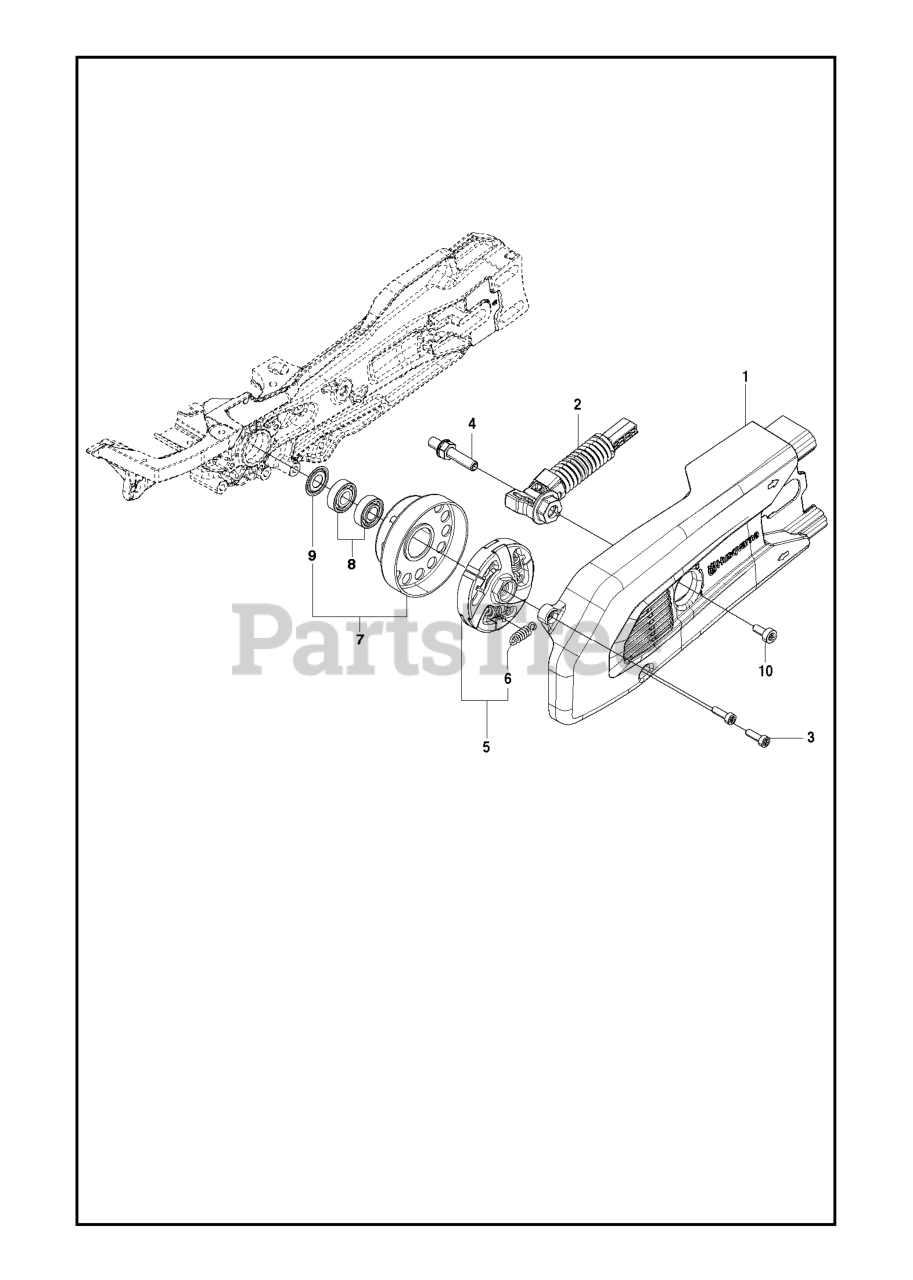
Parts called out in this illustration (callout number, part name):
1	BELT GUARD ASSY
2	BELT TENSIONER ASSY
5	CLUTCH COMPLETE
7	DRIVING PULLEY ASSY 4PK 16"
7	DRIVING PULLEY ASSY 4PK 12" 14
8	HOLDER BALL BEARING
9	DUST COVER
